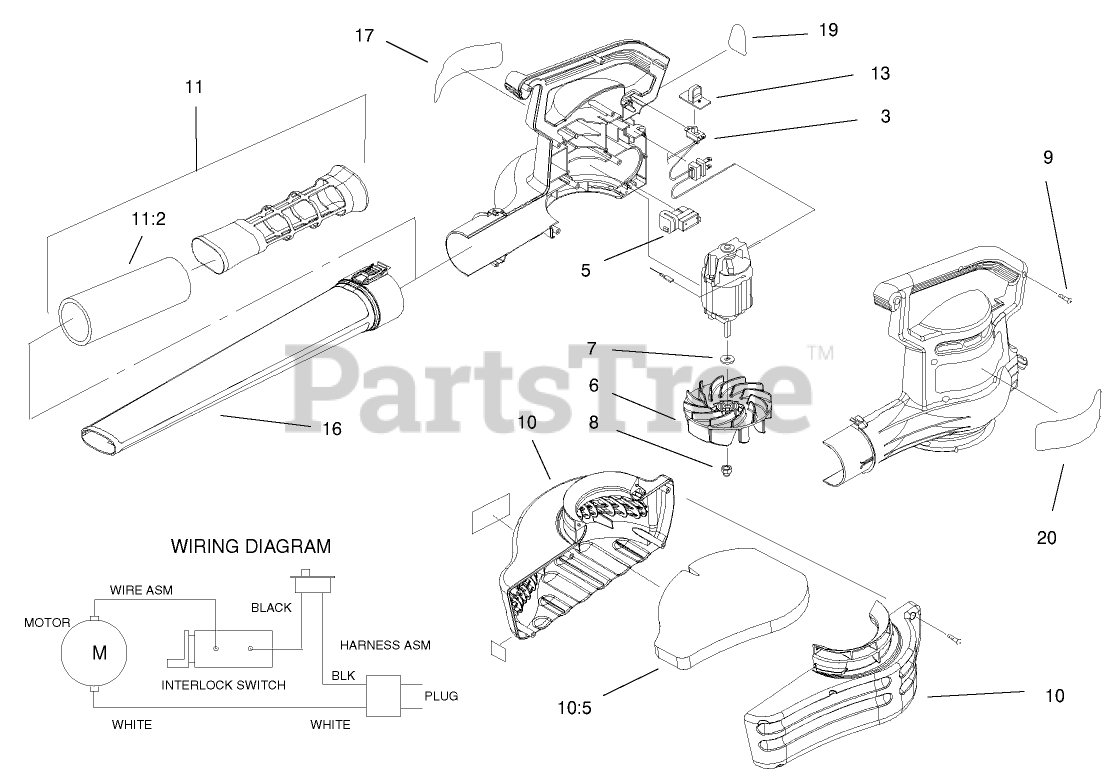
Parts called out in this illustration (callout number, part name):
3	WIRE HARNESS
5	SWITCH - INTERLOCK
6	IMPELLER - BLOWER
7	WASHER
8	NUT-HEX
9	SCREW-PPH
10	ASM-QUIETECH INLET COVER
10:5	FOAM - INLET
11	ASM-Quietech Tube Insert
11:2	FOAM - INSERT
16	TUBE-BLOWER LONG
17	DECAL - WARNING
19	DECAL - INFORMATION
20	DECAL, LOGO, SUPRBLWR
